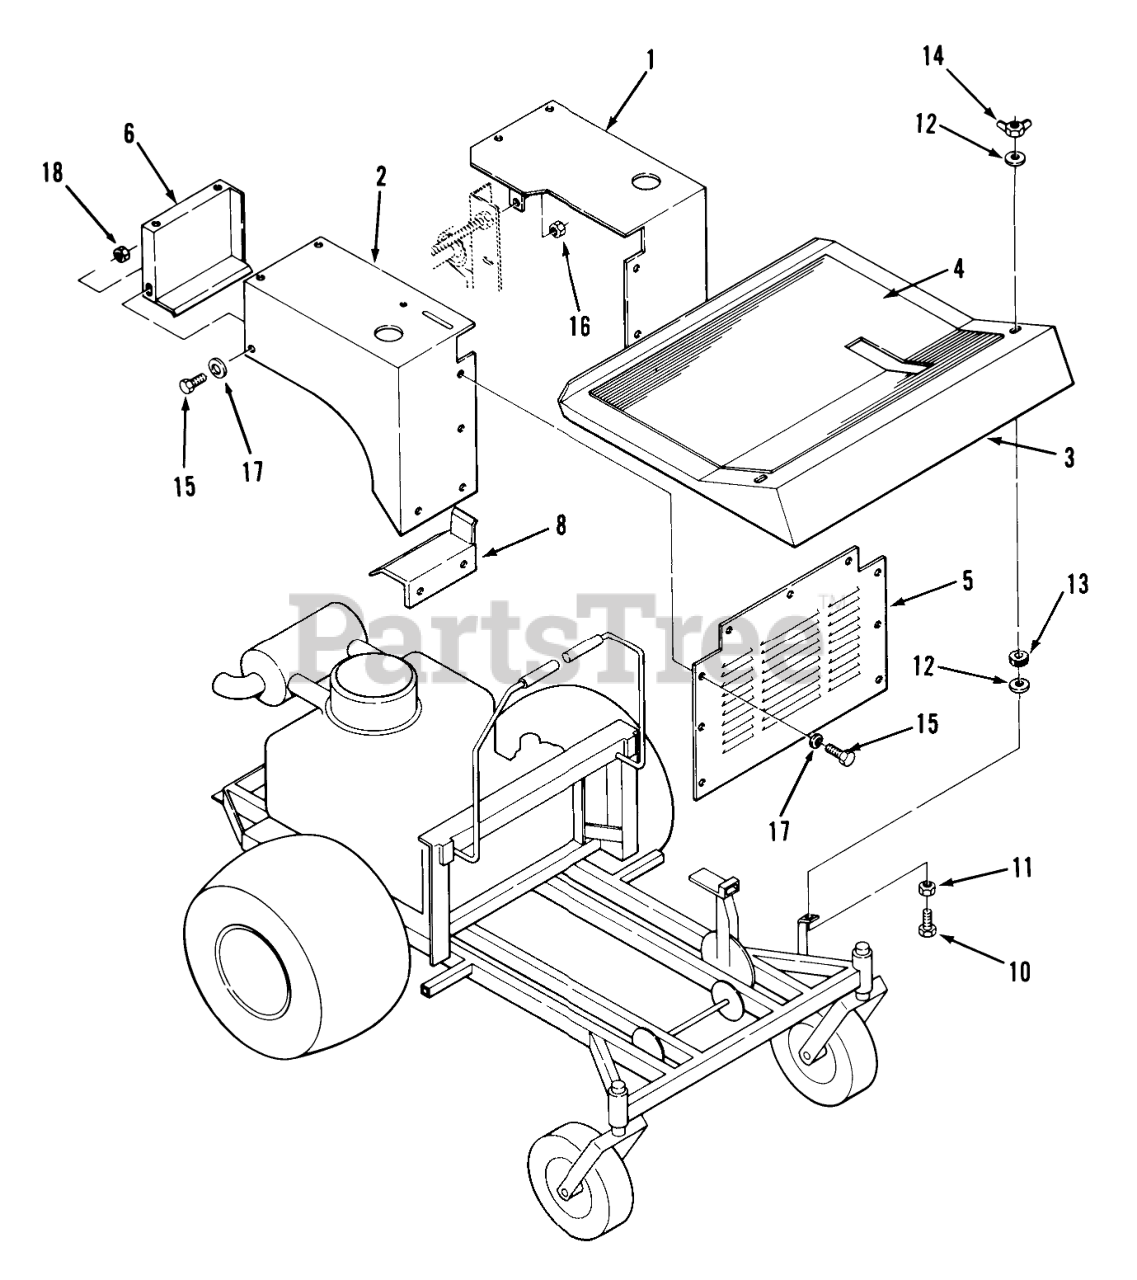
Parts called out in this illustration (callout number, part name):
1	Fender LH
2	Fender RH
3	Floor Pan
4	Footrest Pad Neoprene
5	Front Panel
6	Bracket-Fender Rear RH
6	Bracket-Fender Rear LH
8	Bracket-Fender Frt RH
8	Bracket-Fender Frt LH
10	Hex Bolt 5/16-18 x 1 1/2
11	Nut
12	Washer
13	Rubber Washer
14	WING NUT
15	Bolt
16	Eslok Nut
17	WASHER
18	Nut 1/4-20
